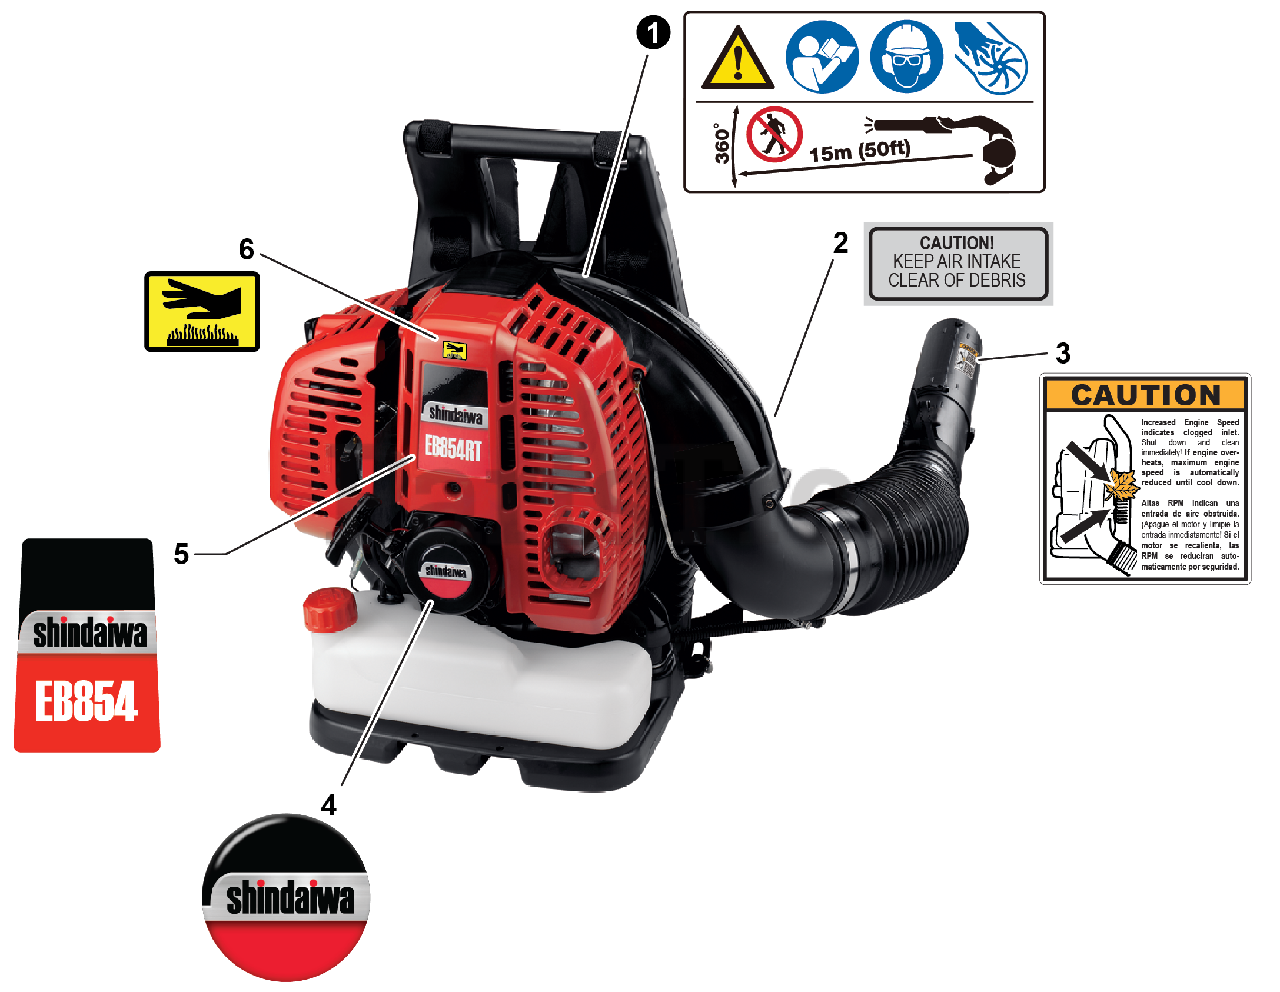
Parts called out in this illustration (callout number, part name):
1	LABEL, CAUTION
2	LABEL, CAUTION - AIR INTAKE
3	LABEL, CAUTION - CLOGGED INLET
4	LABEL, RECOIL STARTER
5	LABEL - MODEL EB854
6	LABEL, CAUTION - HOT
